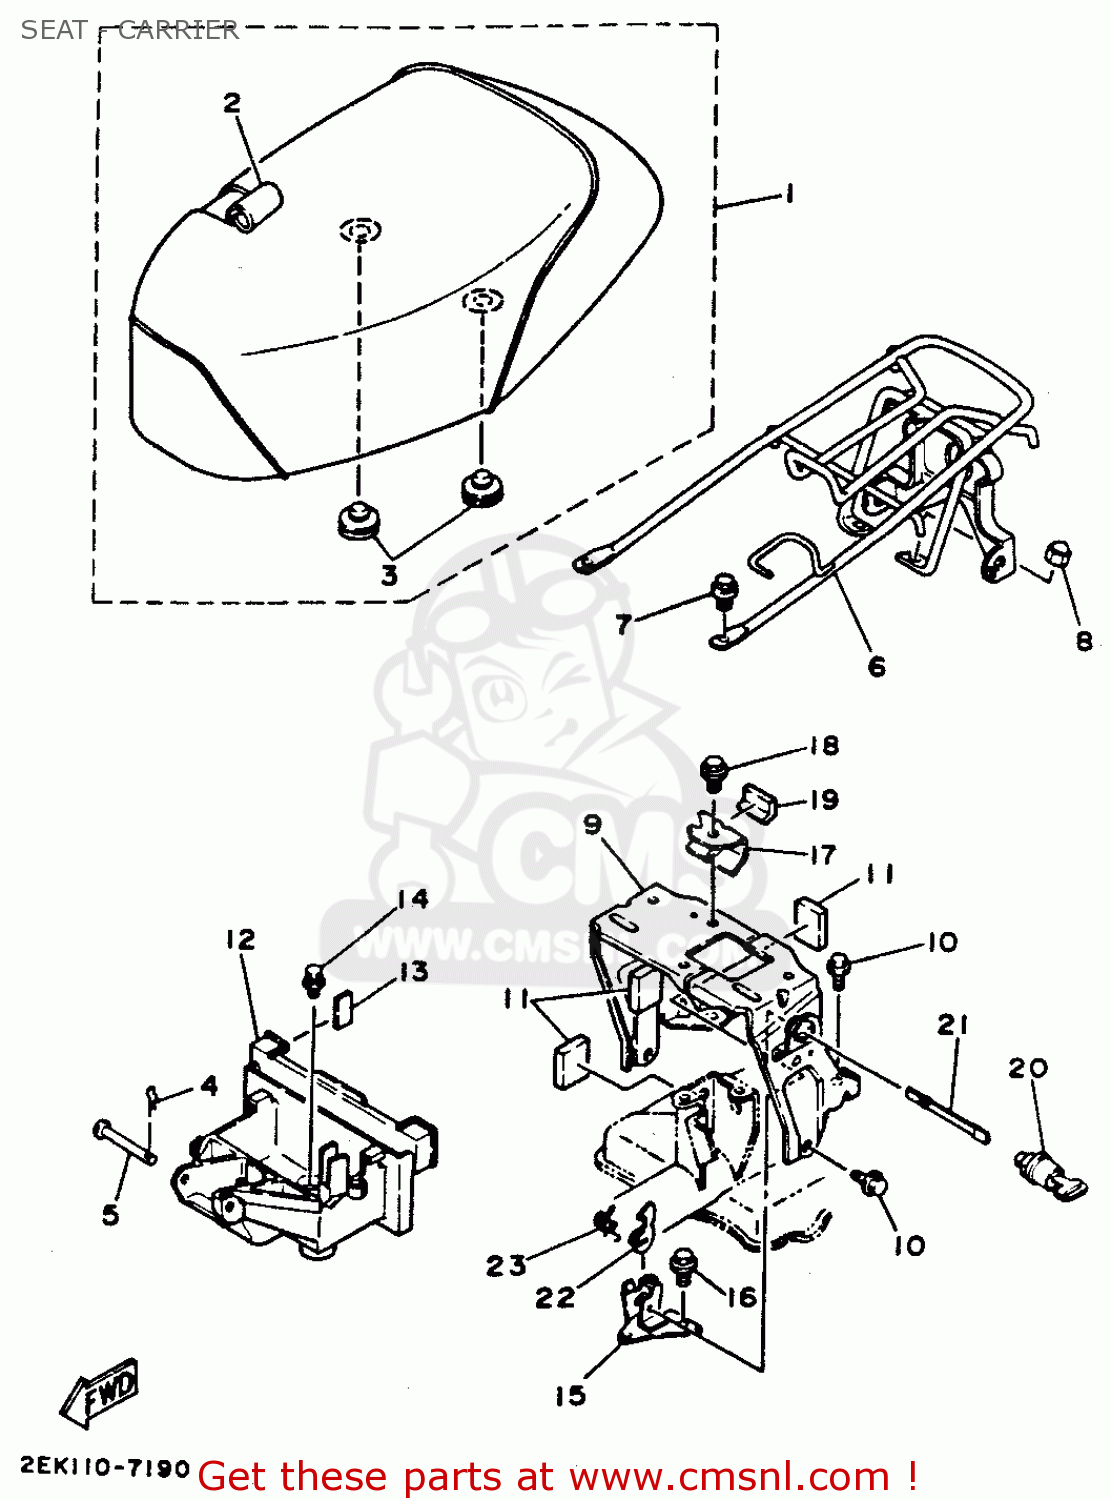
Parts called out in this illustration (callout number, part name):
1	SINGLE SEAT ASSY
2	COVER, SINGLE SEAT
3	PAD, SEAT
4	CLIP 136253750000
5	PIN, CLEVIS (2E9)
6	CARRIER, REAR
7	BOLT, FLANGE (4H7)
8	NUT, CROWN (21G)
9	PLATE, BRIDGE
10	BOLT, WASHER BASED(53L)
11	SEAT, BATTERY
12	BOX, TOOL
13	DAMPER, LOCATING 1
14	BOLT, HEXA W/W
15	STAY, FRONT 1
16	BOLT, FLANGE(1LN)
17	HOLDER 1
18	BOLT, FLANGE(1LN)
19	PAD, BATTERY
20	SEAT LOCK ASSY
21	ARM
22	HOOK, SEAT
23	SPRING, TORSION(53L)
